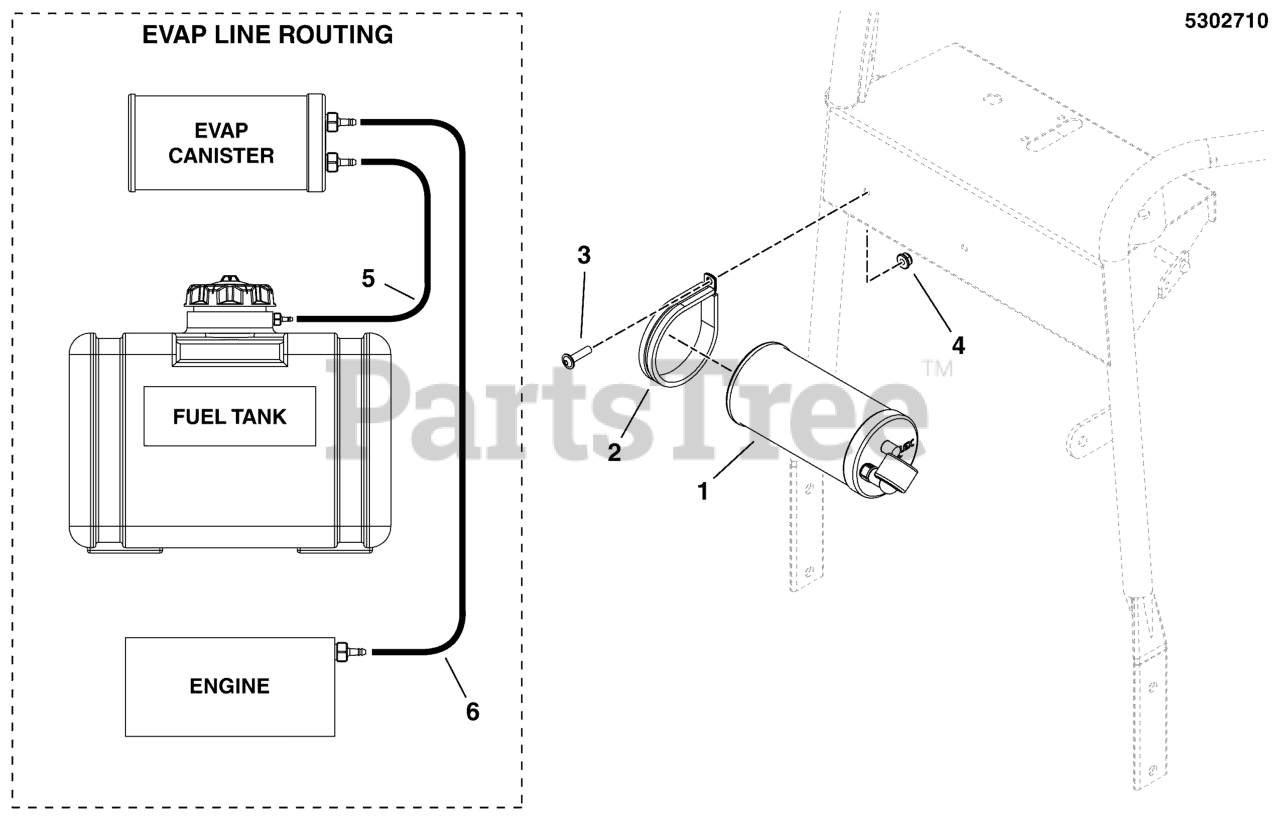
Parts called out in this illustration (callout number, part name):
1	CNSTR, CARB, 6 GAL
2	CLAMP, 3" ID, CUSHIONED, STAINLESS
4	NUT, 1/4-20 HEX NYLOCK FLANGE
5	HOSE, VAPOR, 5MM ID, 8.00 LG
6	HOSE, VAPOR, 5MM ID, 56.00 LG
7	DECAL, EPA CERT, WALKS
